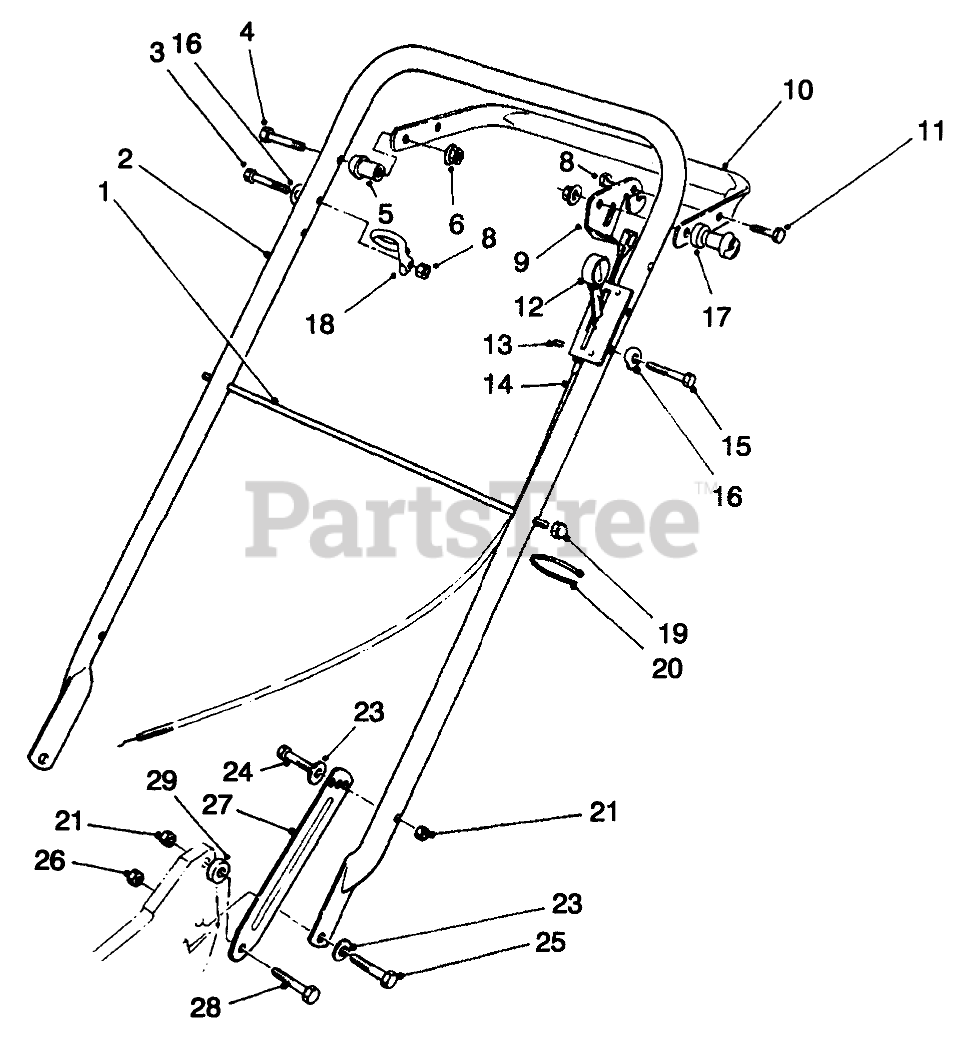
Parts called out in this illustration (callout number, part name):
1	ROD-SUPPORT, BAG
2	Handle
3	SCREW-HH
4	SCREW-HH
5	SPACER-SUPPORT
6	NUT-LOCK, NI
8	NUT-LOCK, NI
9	LEVER-CONTROL
10	Bar-Control
11	SCREW-HH
12	CONTROL-THROTTLE
13	E-RING
14	CABLE-THROTTLE
15	SCREW-HH
16	WASHER
17	SPACER-NYLON
18	GUIDE-ROPE
19	NUT-CAP
20	TIE-CABLE
21	NUT-LOCK, NI
23	WASHER-BELLEVILLE
24	SCREW-HH
25	SCREW-HH
26	NUT-LOCK, NI
27	Latch-Handle
28	SCREW-SHOULDER
29	SPACER
